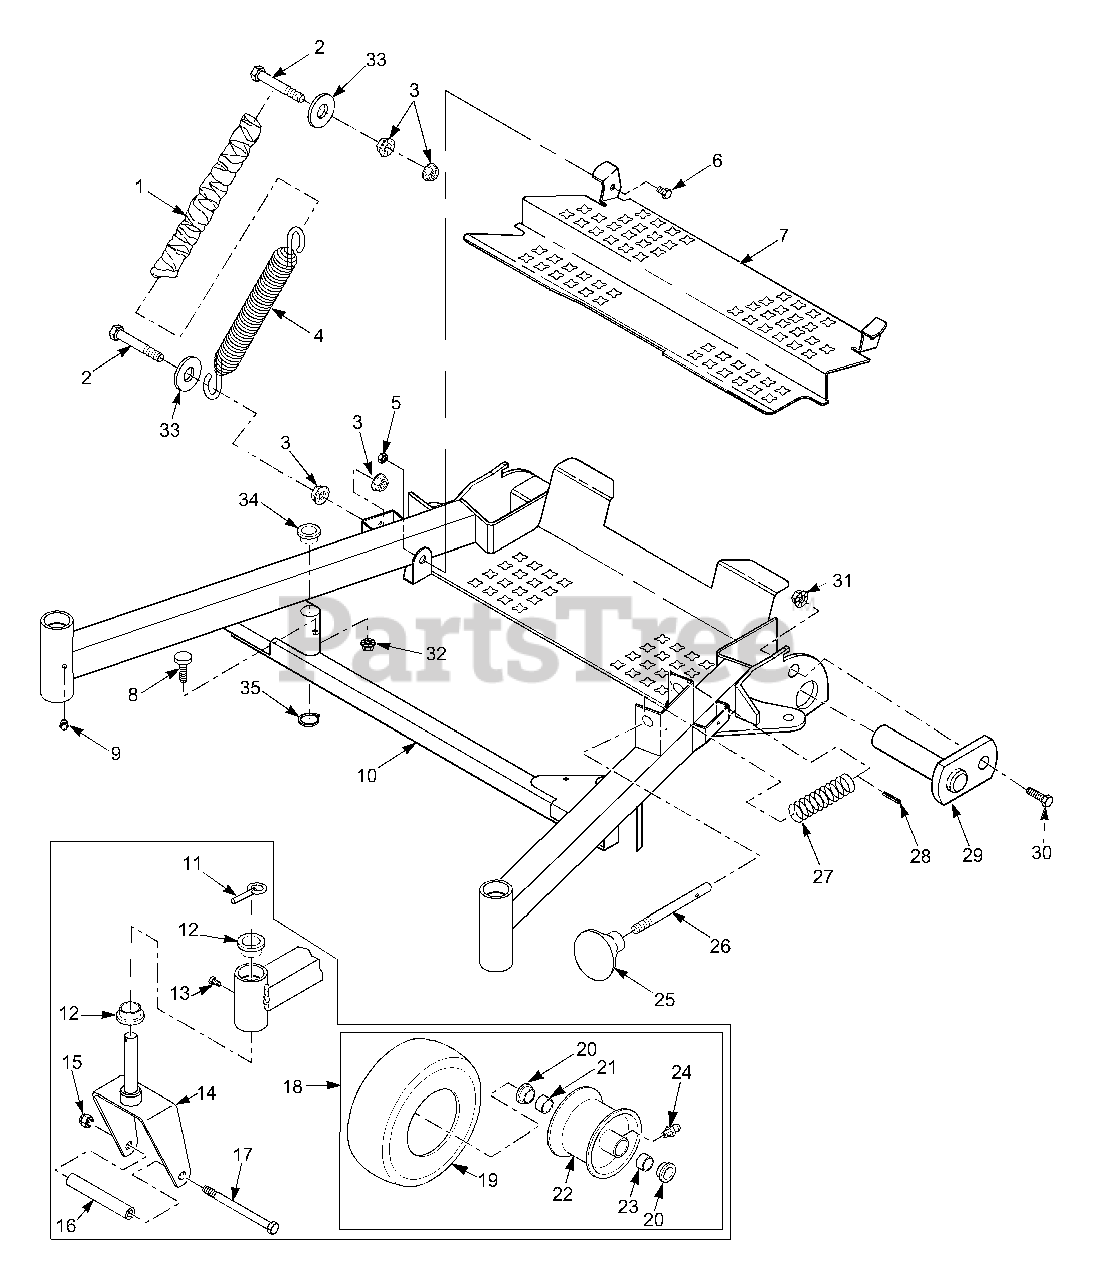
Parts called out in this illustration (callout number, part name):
1	Cover, Spring
2	Bolt, Hex Head 1/2-13 x 2.5"
3	Nut, 1/2-13 Serrated Flange
4	Spring, Cutter Deck LIft
5	Nut, 3/8-16 Elastic Stop
6	Bolt, Hex Head 3/8-16 x 1"
7	Footplate
8	Bumper, Rubber
9	Fitting, Grease
10	Frame, Cutter Deck Mounting
11	Pin, Quick
12	Bushing, 1" ID Oilite
13	Plug, 1/4-28
14	Yoke, Caster
15	Nut, 1/2-13 Elastic Stop
16	Spacer
17	Bolt, Hex Head 1/2-13 x 6.5"
18	Wheel, Caster 11 x 4.0-5
19	Tire, 11 x 4.0-5
20	Retainer
21	Roller Bearing .625 x 3.25"
22	Rim, 5.0 x 3.25"
23	Roller Bearing .625 x 1.0"
24	Fitting, Grease
25	Knob, Cutter Deck Release
26	Rod, Threaded
27	Spring
28	Pin, Roll 3/16 x 1.5"
29	Pin, Deck Frame Pivot
30	Bolt, Carriage 5/16-18 x 1"
31	Nut, 5/16-18 Elastic Stop
32	Nut, 5/16-18 Serrated Flange
33	Flatwasher, 5/8-.688 x 1.750 x .134
34	Bushing
35	Snap-Ring
